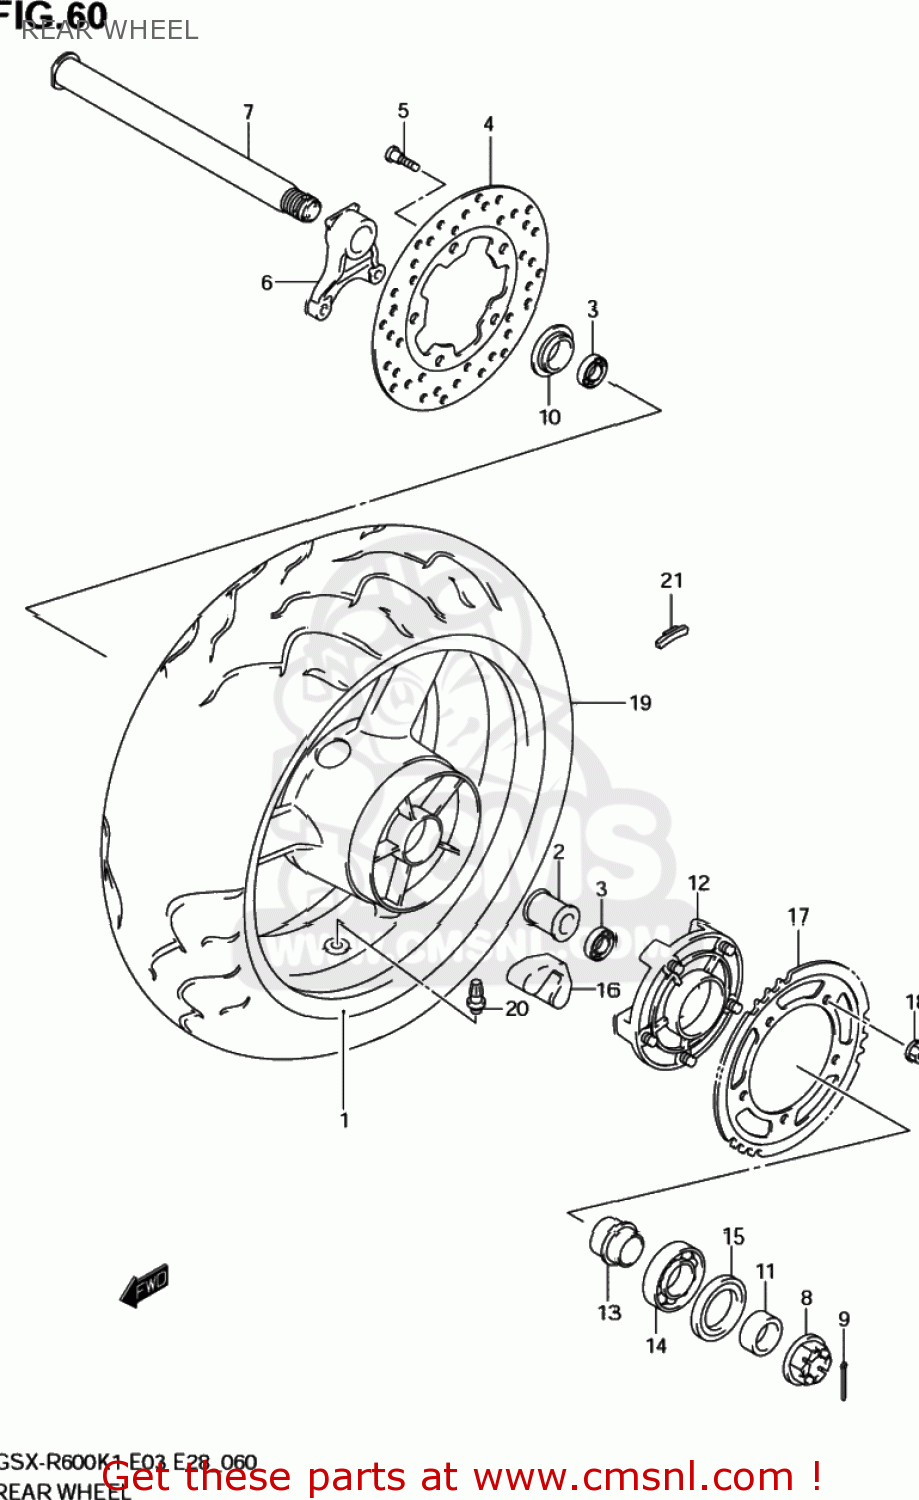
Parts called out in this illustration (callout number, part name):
1	WHEEL,REAR,17X
2	SPACER,REAR HUB BEARING
3	BEARING(28X52X12)
4	DISC,RR BRAKE
5	BOLT(8X33)
6	BRACKET,RR CALIPER
7	AXLE,RR
8	NUT
9	PIN, COTTER
10	SPACER,RR AXLE,R
11	SPACER,RR AXLE,L
12	DRUM, REAR SPROCKET
13	RETAINER,RR SPROCKET DRUM
14	BEARING
15	SEAL,OIL(39X65X7)
16	ABSORBER,RR HUB SHOCK
17	SPROCKET,RR(45T-525)
18	NUT
19	TIRE, REAR,180/55 ZR17 (73W)
20	VALVE ASSY,WHEEL RIM(TR412)
21	WEIGHT,BAL. 30
